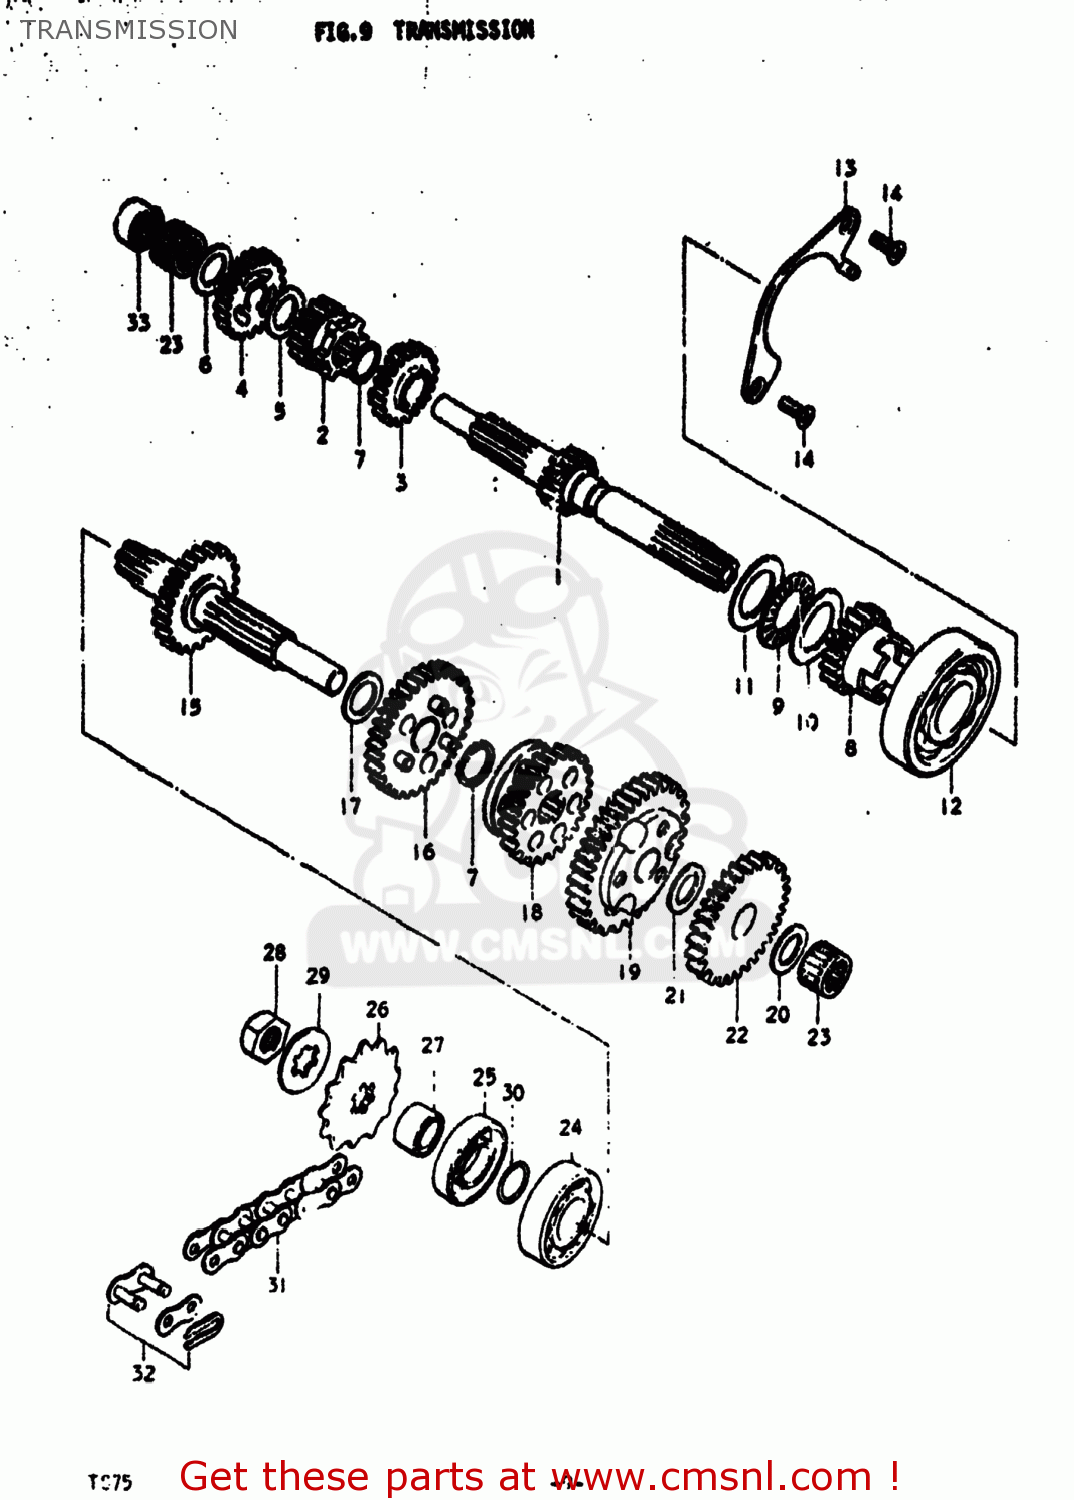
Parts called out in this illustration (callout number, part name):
1	SHAFT,COUNTER
2	GEAR,SECOND DRIVE
3	GEAR,THIRD DRIVE
4	GEAR,FOURTH DRIVE
5	WASHER(12X24X1.5)
6	WASHER
7	CIRCLIP
8	GEAR,KICK STARTER DRIVE
9	BEARING(20.1X35X2.8)
10	WASHER (20.1X29.5X0.8)
11	WASHER(20X34X0.8)
12	BEARING
13	PLATE,COUNTERSHAFT BEARING
14	SCREW
15	SHAFT,DRIVE
16	GEAR,SECOND DRIVEN
17	WASHER
18	GEAR,3RD DRIVEN
19	GEAR,FIRST DRIVEN
20	WASHER
21	WASHER(12X24X1.5)
22	GEAR,KICK STARTER IDLE
23	BEARING(12X19X12)
24	BEARING
25	SEAL,OIL(21X40X7)
26	SPROCKET(NT:15)
27	SPACER(17.3X25X79.5)
28	NUT
29	WASHER,LOCK
30	O RING(D:1,ID:16.8)
31	CHAIN ASSEMBLY,DRIVE
32	JOINT ASSEMBLY,CHAIN
33	SEAL,OIL(5.5X16X8)
